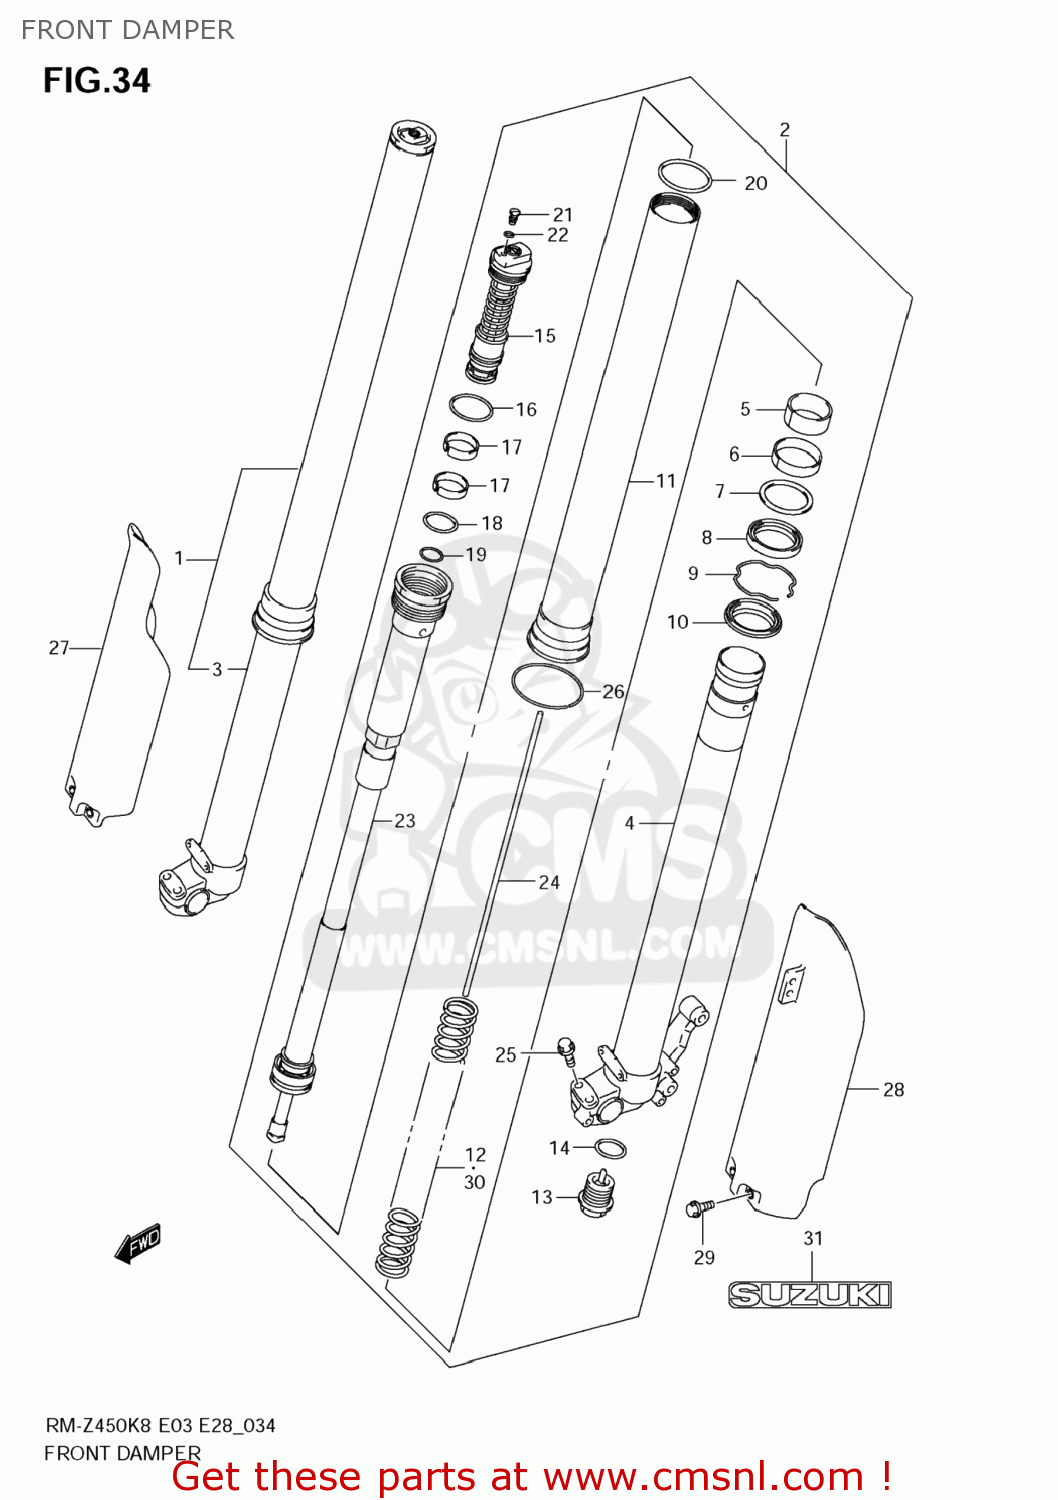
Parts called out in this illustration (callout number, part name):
1	DAMPER ASSY,FR FORK,R
2	DAMPER ASSY,FR FORK,L
3	TUBE,INNER,R
4	TUBE,INNER,L
5	BUSH
6	BUSH,GUIDE
7	SPACER,SEAL
8	SEAL,OIL
9	RING,OIL SEAL STOPPER
10	SEAL,DUST
11	TUBE,OUTER
12	SPRING,FR(K=0.5)
13	BOLT,CTR
14	O RING
15	BOLT
16	O RING
17	BUSH
18	O RING
19	O RING
20	O RING
21	BOLT,PLUG
22	O RING,PLUG
23	DAMPER
24	ROD,PUSH
25	BOLT
26	STOPPER,RING
27	PROTECTOR,FR FORK,R
28	PROTECTOR,FR FORK,L
29	BOLT(6X10)
30	SPRING,FR(K=0.45)
31	EMBLEM,SUZUKI
